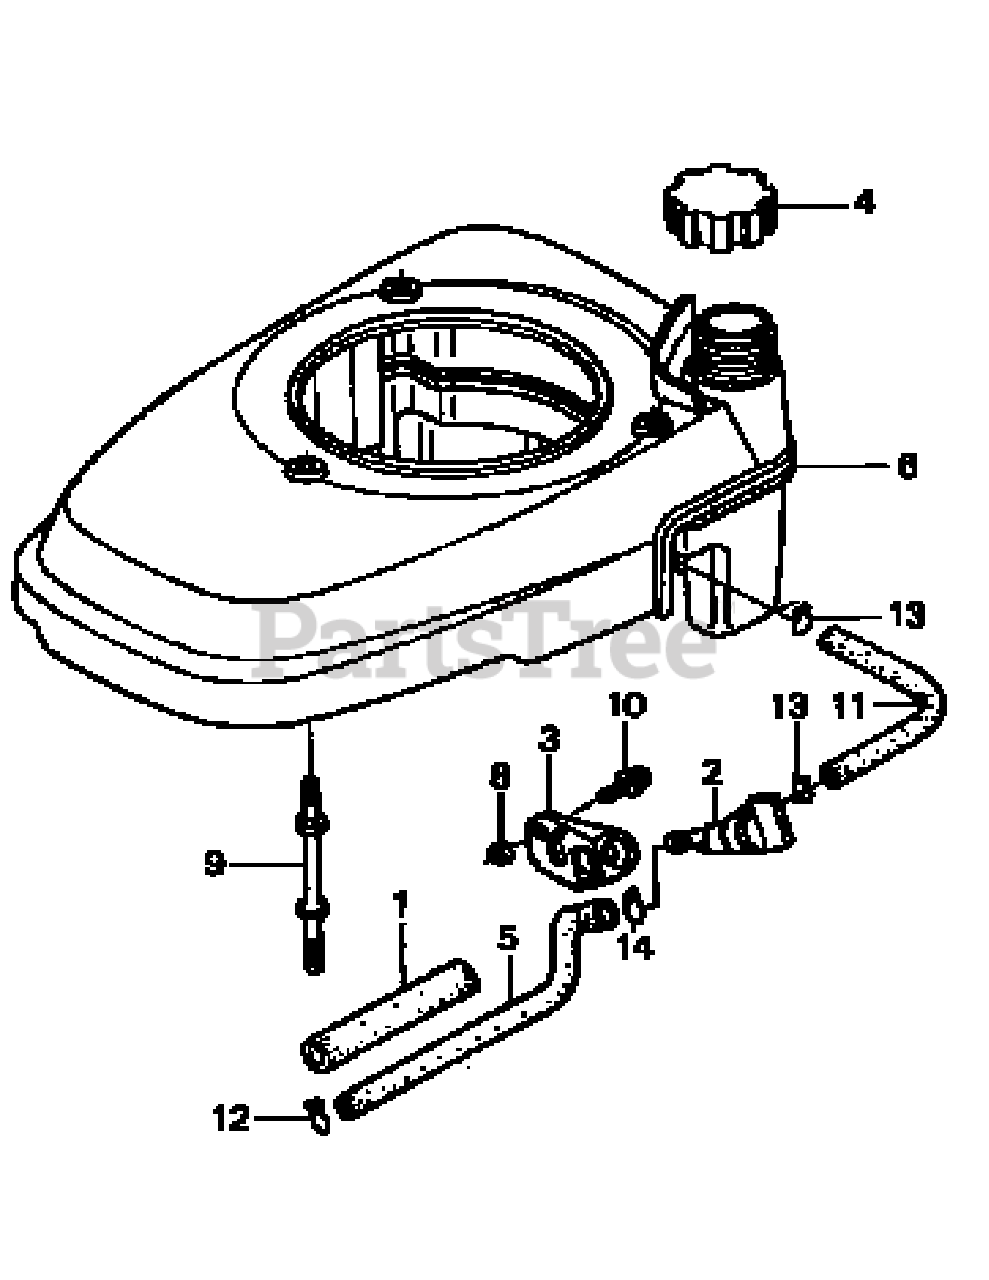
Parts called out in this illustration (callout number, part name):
1	Supporter Rubber
2	Petcock Assy.
3	Petcock Bracket
4	Fuel Tank Cap Assy.
6	Fan Cover
8	Fuel Petcock Collar
10	Screw Washer
11	Fuel Tank Tube
12	Tube Clip
13	Tube Clip
14	Tube Clip
